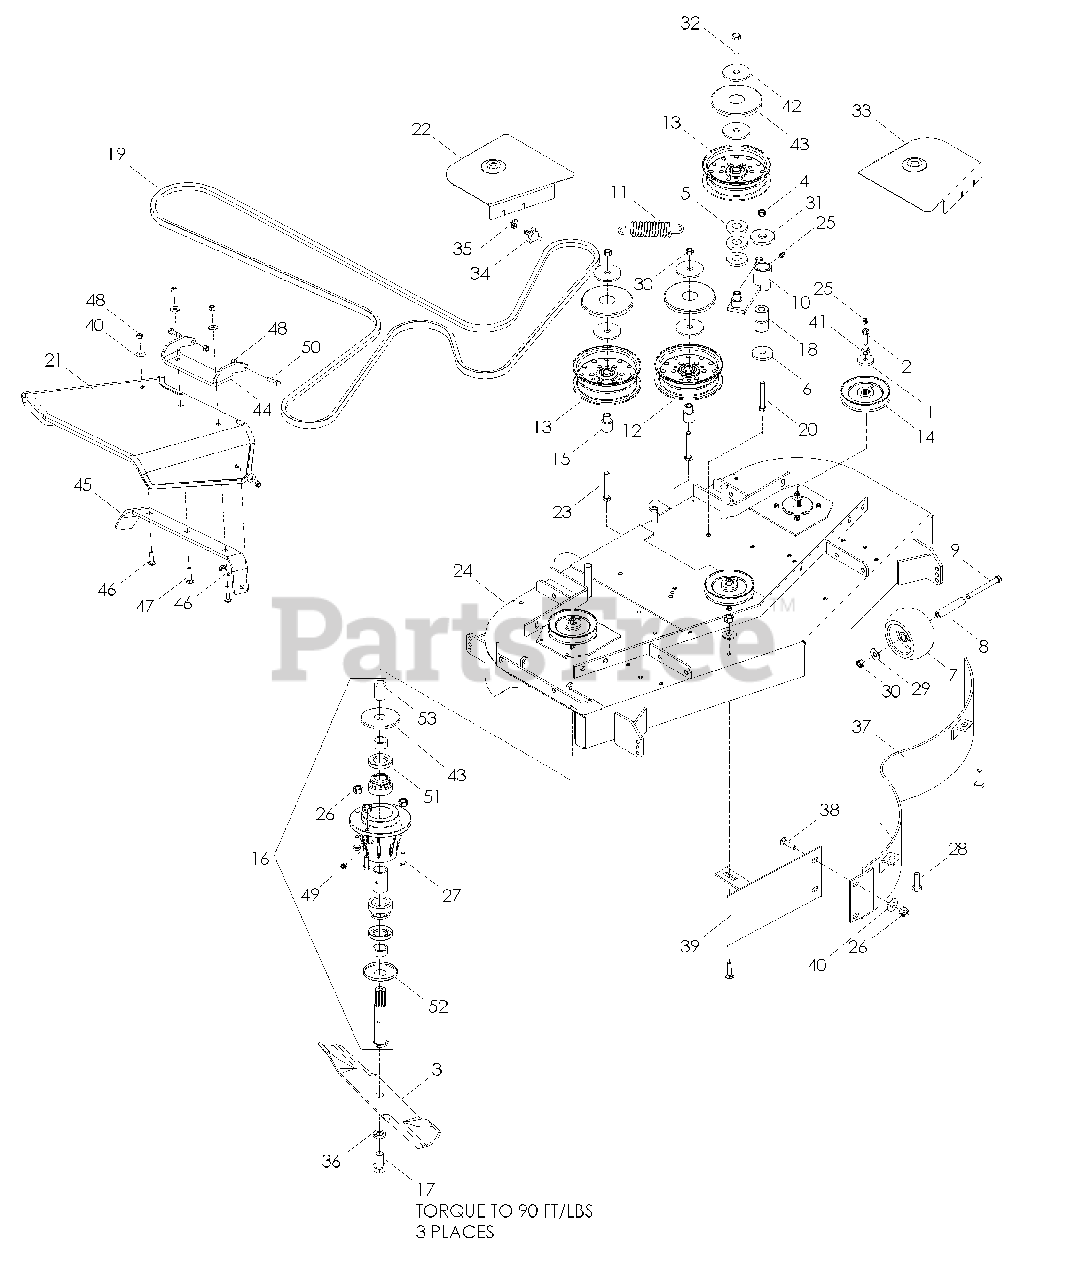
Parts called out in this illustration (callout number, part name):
1	WASHER, HEAVY
2	HCS 7/16-20 x 1 1/2 GR8 SPEC
3	BLADE, 18"
4	NUT 1/2-13 HEX NYLOC
5	BUSHING 5/8 MACHINERY
6	WASHER, SUPPORT
7	ROLLER, ANTI-SCALP
9	HCS 3/8-16 x 31/2 GR8
10	ARM, IDLER
12	PULLEY, IDLER
13	PULLEY, IDLER
15	BUSHING, IDLER
16	SPINDLE ASM
17	HCS 5/8-18 x 1 1/4
18	BUSHING, PIVOT
19	BELT, DECK
20	HCS 1/2-13 x 3 1/4
21	CHUTE, RUBBER
22	SHIELD, RT
23	HCS 3/8-16 x 3
24	DECK W/DECALS
25	ZERK
26	NUT 5/16-18 HEX CTRLK
27	HCS 5/16-18 x 1
28	HCS 5/16-18 x 3/4
29	WASHER 3/8 FLAT
30	NUT 3/8-16 HEX CNTRLK
31	WASHER 1/2 STD FLT
32	HCS 3/8-16 x 1 1/4
33	SHIELD LT
34	KNOB W/STUD
36	WASHER 5/8 SLW
37	MAIN WLDMT
38	RHSNB 5/16-18 x 5/8
39	CENTER WLDMT
40	WASHER 5/16 STD FLT
41	WASHER 7/16 SLW
42	WASHER 3/8 SPECIAL
43	DUST CAP, TOP
44	BRACKET, PIVOT
45	REINFORCEMENT, BRACKT
46	RHSNB 5/16-18 x 1 1/4
47	RHSNB 5/16-18 x 1 1/2
48	NUT 5/16-18 HEX NYLOC
49	GREASE POPPET
50	HCS 5/16-18 x 1 1/4
51	SEAL, SHAFT
52	DUST CAP, BOTTOM
53	CAP, VINYL
